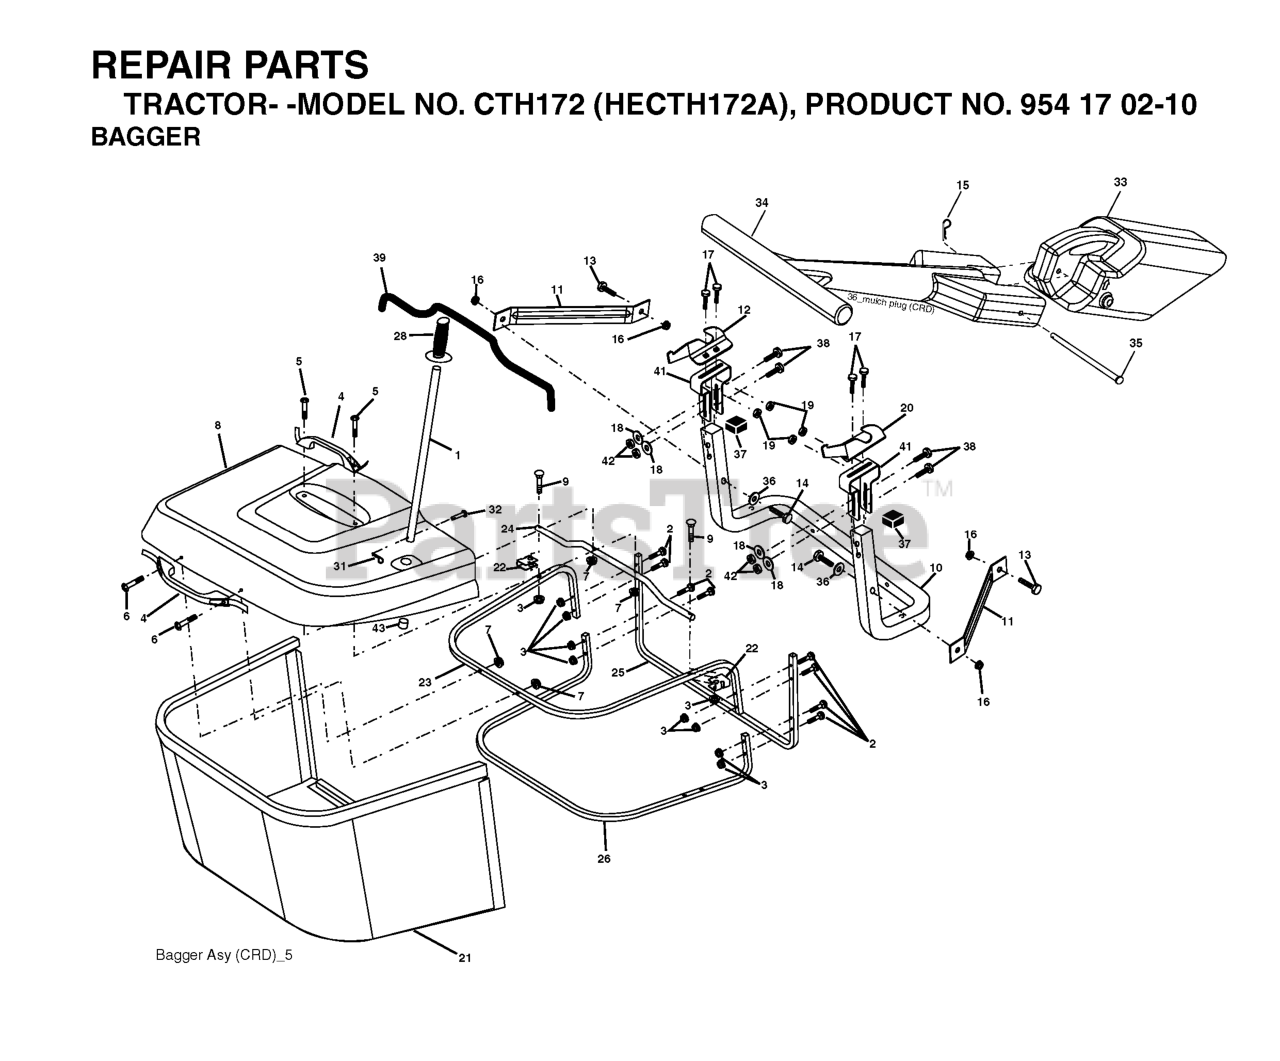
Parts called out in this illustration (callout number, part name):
1	TUBE HANDLE
2	Bolt Carriage 1/4-20 x 2.0 Gr.5
3	NUT T
4	HANDLE.BAGGER.W/LVRS.BLK.CRD
5	SCREW.PAN.HEAD
6	REPL BY 532 75 00-29
8	COVER.PNT.BGR.CRD.WSLOTS.MS668
9	Bolt Carriage 1/4-20 x 2.25d x Gr.5
10	TUBE
11	BRACKET.SUPPORT.UPPER.BAG.CRD
14	BOLT-HEX EAK
15	RETAINER-SPRNG RB
16	NUT LOCK FLG 3/8-16 UNC
17	RP BOLT 5/16-18 X3/4 ZN/YEL GR
18	WASHER M
19	NUT LOCK HEX FLANGE 5/16-18
20	BRACKET
21	GRASS BAG
22	BRKT.SIDE.BAG.CRD
23	TUBE.UPPER.BAG.CRD
24	TUBE.PIVOT.BAG.CRD.BLACK
26	TUBE.LOWER.BAG.CRD
28	GRIP.HANDLE.BLACK
31	RETAINER CLIP
32	RIVET,DRILLED
33	MULCH PLUG, CTH150
34	HANDLE.MULCHER.92.CRD (2 2)
36	WASHER
37	Plug Support Bagger CRD
38	BOLT.5/16-18X2.5
39	SEAL.TRIM.37'
41	BRKT.VERT.ADJ.BAGGER.CRD
42	NUT.71038.31-18.HEX.NYLOCK
43	PLUG, TUBING END
